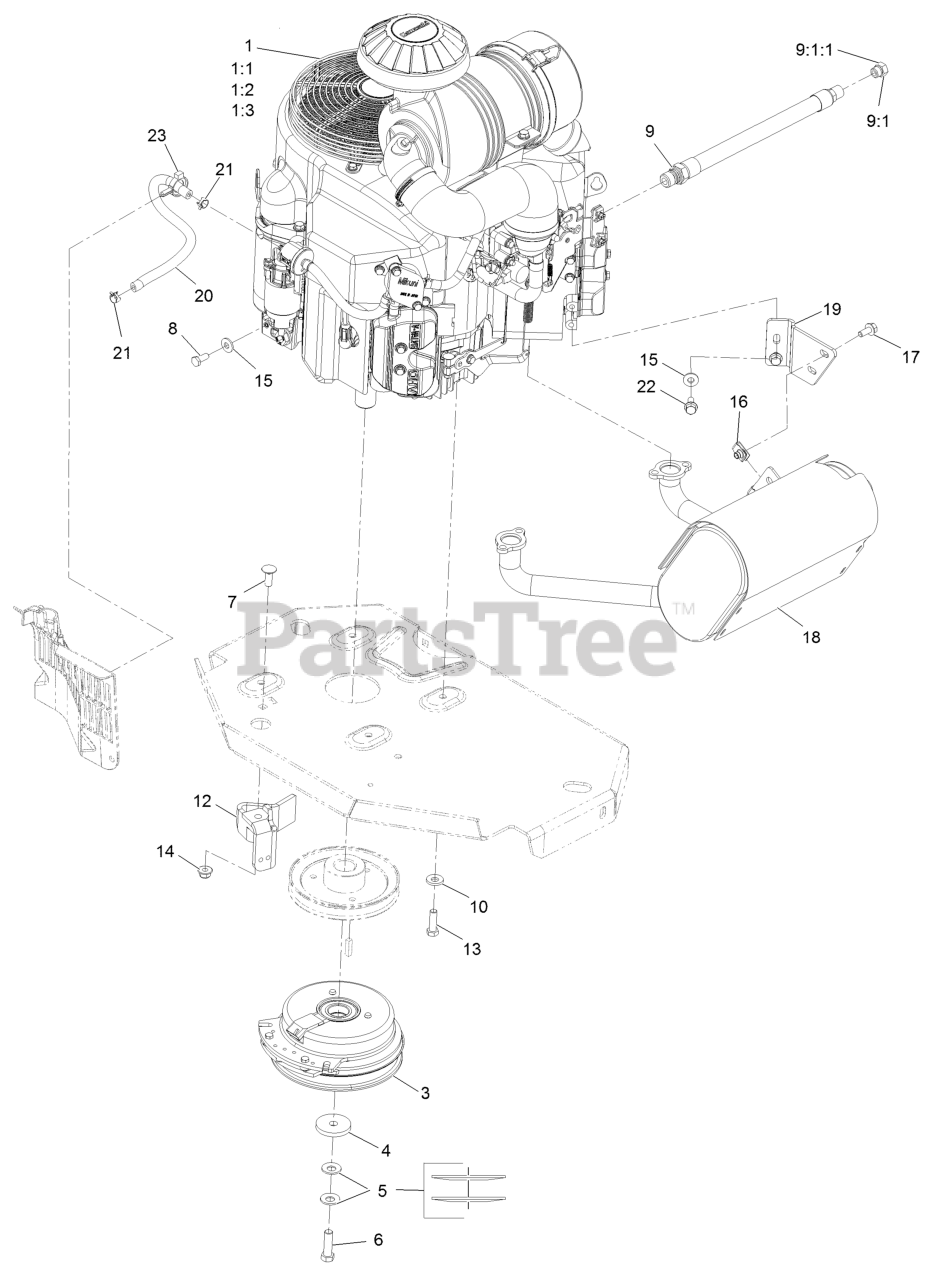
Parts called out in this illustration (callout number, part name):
1:1	Kawasaki 49065-2078 Engine Oil Filter
1:2	Kawasaki 11013-7044 Engine Air Filter
1:3	Kawasaki 11013-7045 Safety Filter
3	CLUTCH KIT
4	WASHER-CLUTCH
5	WASHER-SPRING
6	SCREW-HH 7/16-20 X 1 1/2 W/LOCTITE
7	SCREW-CARR
8	SCREW-HH
9	ENGINE OIL DRAIN HOSE ASM
9:1	PLUG-HH
9:1:1	O-RING
10	WASHER-BELLEVILLE
12	CLUTCH-ANCHOR
13	SCREW-HH
14	NUT-HF, NI
15	WASHER-SPRING
17	SCREW-HHF
18	MUFFLER
19	BRACKET-MUFFLER
20	HOSE-FUEL
21	CLAMP-HOSE
22	SCREW-HHF
23	CLAMP-HOSE
